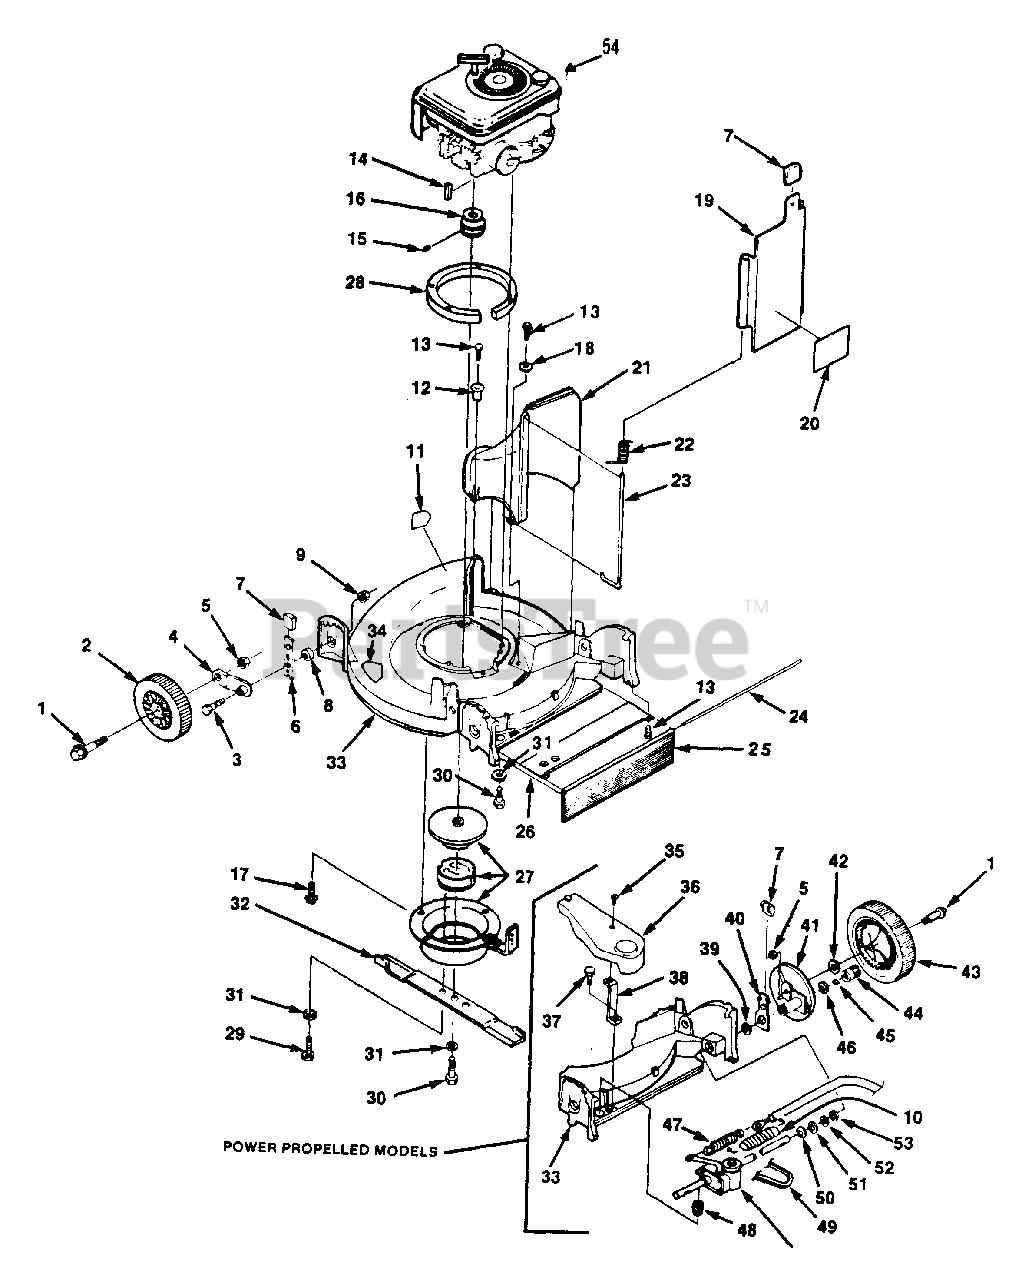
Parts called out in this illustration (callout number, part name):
1	AXLE ASSY
2	WHEEL ASSY
3	BOLT - 5/16 X 18
4	ARM - WHEEL ADJUSTING
5	NUT - 3/8-24
6	INDEXING ASSY
7	KNOB
8	SPACER
9	NUT - 5/16-18 -- FLANGE
10	COVER, SPRING
11	LABEL - WARNING
12	EYELET
13	SCREW - 1/4-20 X 3/4"
14	KEY
15	SCREW - 1/4-20 X 3/8"
16	PULLEY - Drive
17	SCREW - 5/16-18
18	WASHER - 1/4"
19	DOOR, CHUTE
20	LABEL - DOOR
21	CHUTE, DISCHARGE
22	SPRING
23	PIN, HINGE
24	ROD, DRAG FLAP
25	FLAP, DEBRIS
26	COVER - REAR
27	BLADE/BRAKE/CLUTCH
28	RING, ENGINE
29	SCREW - 3/8-16 X 1"
30	SCREW - 3/8-24 X 2"
31	LOCKWASHER - 3/8"
32	BLADE - 21" (53cm)
33	DECK ASSY
34	LABEL - FOOT PAD
35	SCREW - 1/4-20 X 3/4"
36	COVER, DRIVE
37	SCREW - 10-16 X 1/2"
38	SUPPORT-Belt Cover
40	INDEXING ASSY
41	DRIVE WHEEL SUPPORT ASSY
43	WHEEL ASSY
44	PINION - RIGHT HAND
44	PINION - LEFT HAND
45	PAWL
46	WASHER
47	SPRING
49	BELT, DRIVE
50	RING, RETAINING
52	WASHER
53	WASHER
54	ENGINE - M14V-B1ZO
55	GEAR REDUCER ASSY
